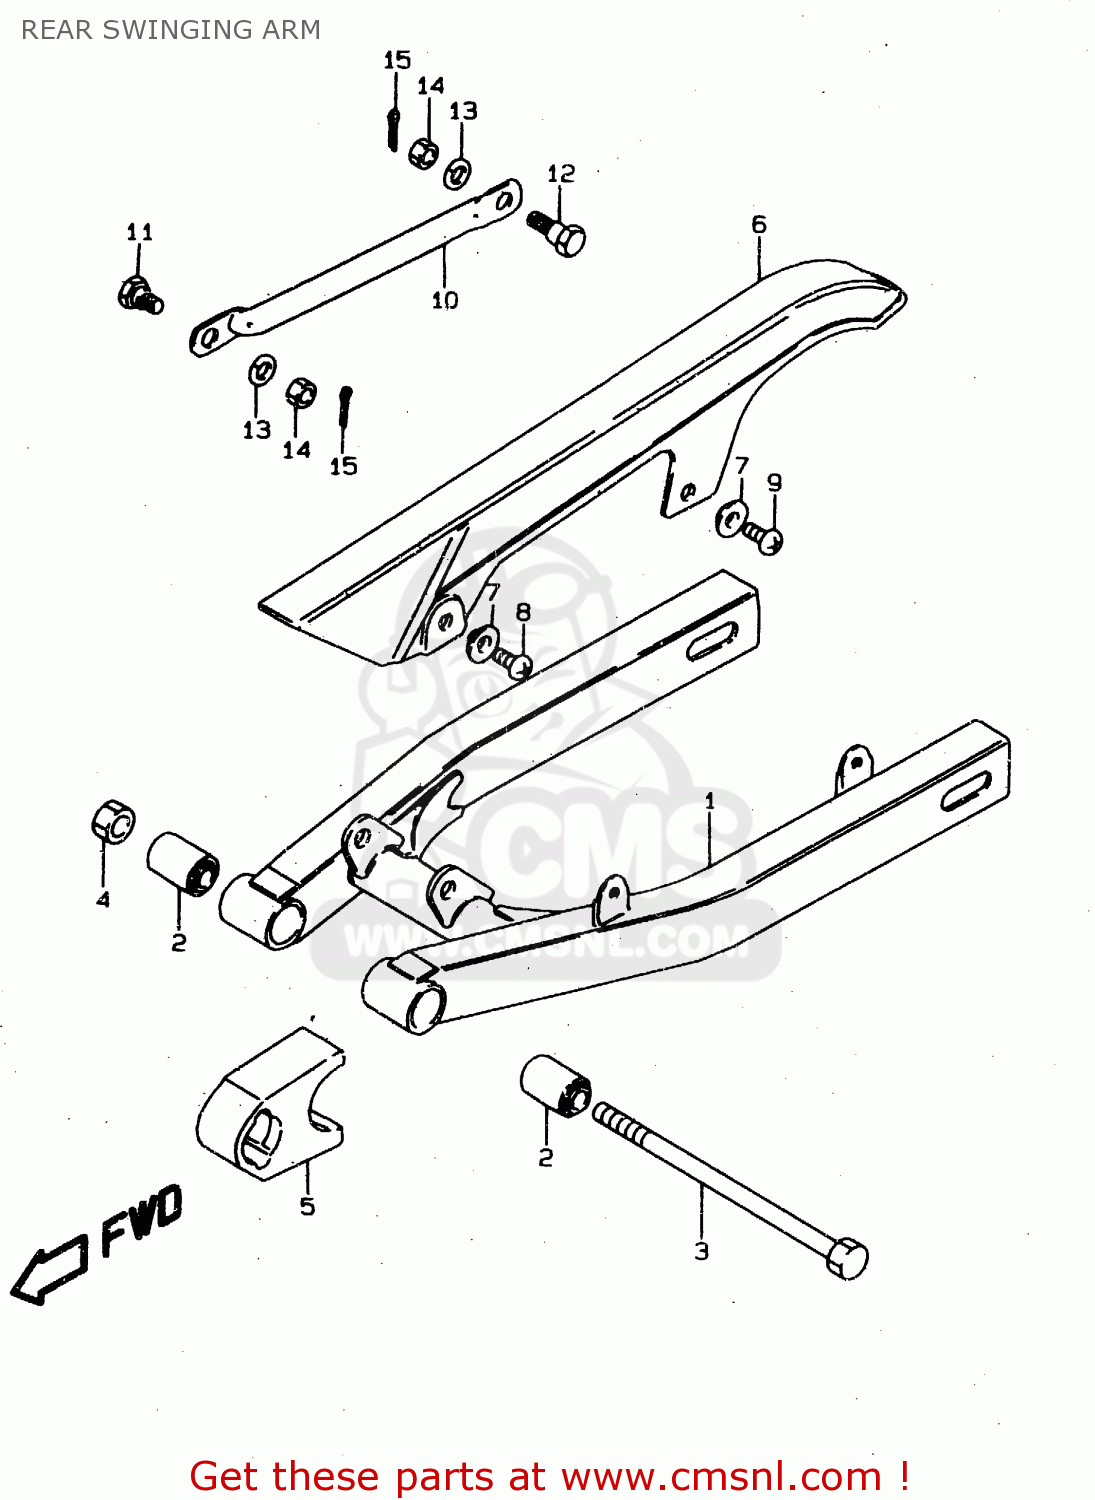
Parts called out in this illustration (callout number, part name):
1	SWINGINGARM ASSY,RR
2	BUSH
3	SHAFT,RR SWINGINGARM PIVOT
4	NUT
5	BUFFER,CHAIN TOUCH DEFENSE
6	CASE,CHAIN
7	WASHER
8	SCREW
9	SCREW
10	TORQUELINK,RR
11	BOLT(8X22)
12	BOLT(8X26.5)
13	LOCK WASHER
14	NUT
15	PIN 20X20
